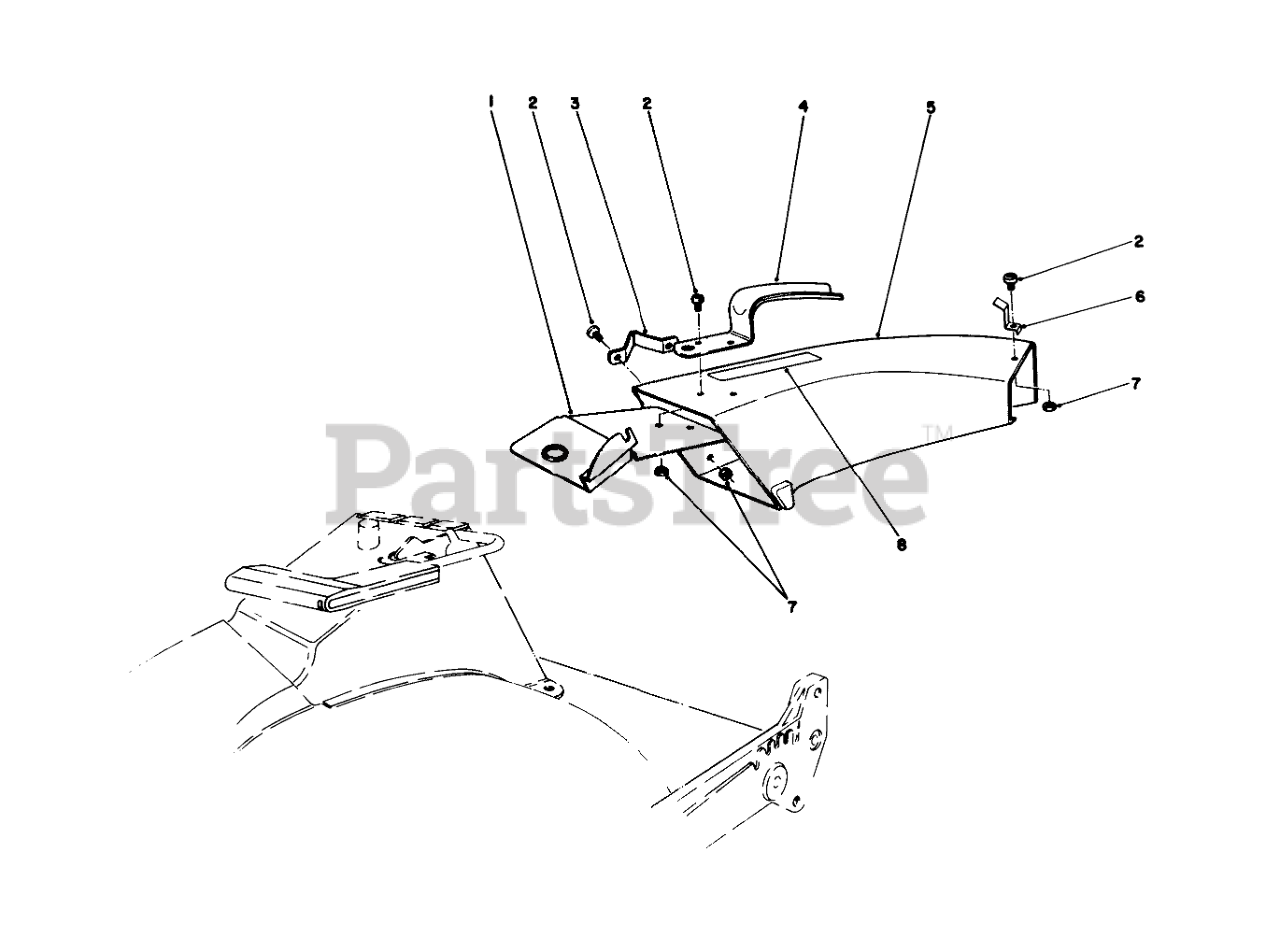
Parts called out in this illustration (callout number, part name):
1	Plate-Discharge Chut
2	10-24 X 5/8 PAN HD MS
3	SIDE BRACKET
4	CHUTE HANDLE
5	Chute-Discharge (Incl. Ref. #8)
7	NUT-LOCK, NI
8	DECAL CAUTION
